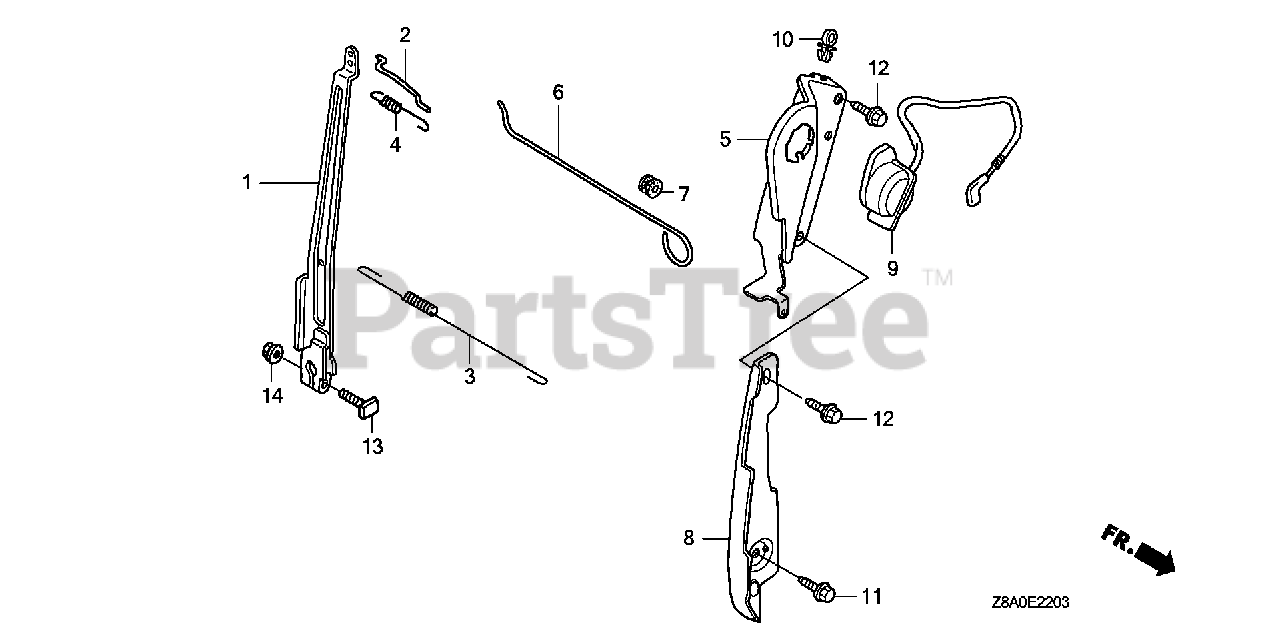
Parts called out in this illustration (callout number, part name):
1	ARM, GOVERNOR
2	ROD, GOVERNOR
3	SPRING, GOVERNOR
4	SPRING, THROTTLE RETURN
5	BASE, CONTROL
6	ROD, CHOKE CONTROL
7	GROMMET, CHOKE ROD
8	PLATE, SIDE
9	SWITCH ASSY., ENGINE STOP
10	HOLDER, WIRE (FASTEX)
10	CLIP A, CABLE (3.8MM BLACK) (NIFCO)
11	BOLT, FLANGE (6X12) (CT200)
12	BOLT, FLANGE (6X14) (CT200)
13	BOLT, GOVERNOR ARM
14	NUT, FLANGE (6MM)
